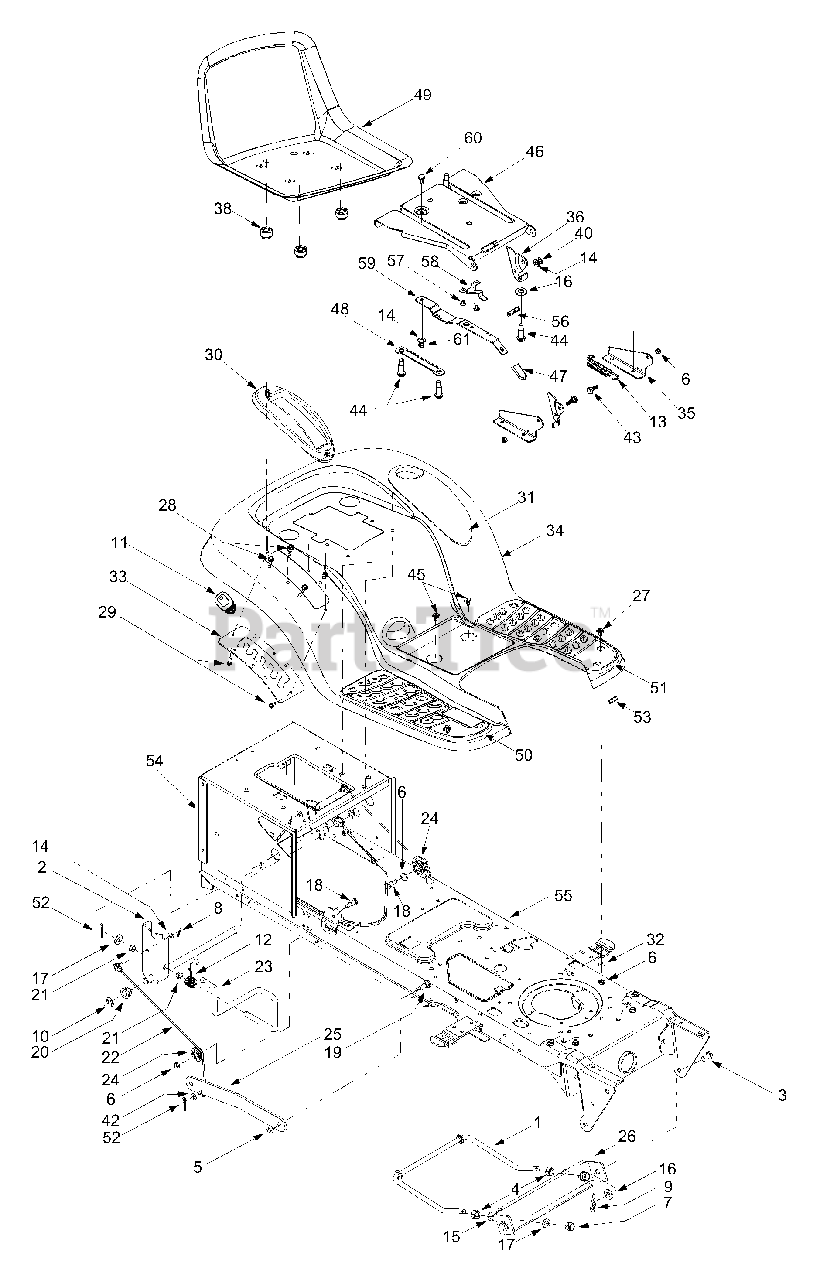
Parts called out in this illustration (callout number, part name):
1	Deck Stabilizer Rod
3	Clevis Pin, .5 x .78
4	Lock Nut, 1/2-13
5	Lock Nut, 3/8-16
6	Lock Nut, 5/16-18
7	Hex Nut, 1/2-13
8	Internal Cotter Pin
9	Internal Cotter Pin
11	Handle Grip: Deck Lift Lever
12	Torsion Spring
13	Extension Spring
14	Flat Washer, 5/16
15	Lock Washer, 1/2
16	Flat Washer, .31 x 1.062 x .134
17	Flat Washer, .51 x 1.12 x .06
18	Hex Cap Screw, 5/16-18 x .62
19	Shoulder Screw, 3/8-16
20	Hex Flange Bearing
21	Snap Flange Bearing
22	Lift Cable, 16.16
24	Roller Pulley
27	Carriage Bolt, 5/16 x .62
28	Self-Tapping Screw, 5/16-18 x .625
29	Self-Tapping Screw, 1/4-15 x .75
30	Lift Lever Cover
31	Cover w/ Cup Holder
32	Flat Washer, .349 x 1.0 x .063
36	Lift Bracket: Seat
37	Hex Flange Lock Nut, 1/4-20
39	Shoulder Screw 3/8-16
41	Spring Washer, .265 x .562 x .025
42	Flat Washer, .344 x .62 x .03
43	Shoulder Screw
44	Shoulder Screw, .50 x .925, 3/8-16
45	Self-Tapping Screw 1/4-20 x 0.5"
48	Seat Adjustment Selector
49	Medium Back Seat, Black
57	B Screw #10-16
60	Shoulder Screw
